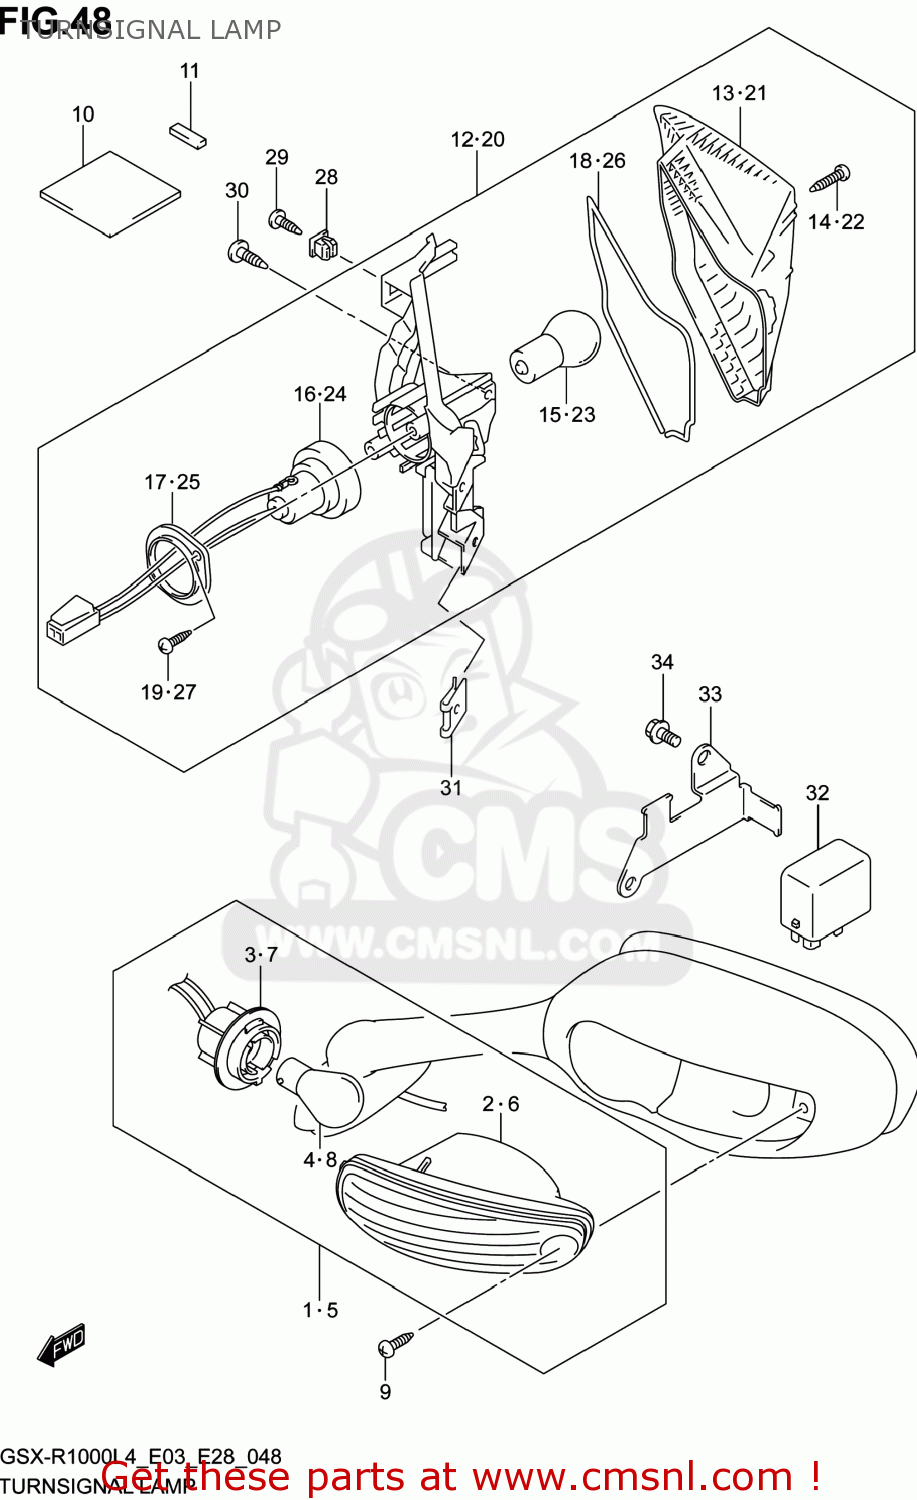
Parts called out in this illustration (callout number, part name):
1	LAMP ASSY,FR TURN SIGNAL,R
2	LAMP UNIT,R
3	SOCKET,R
4	BULB(12V21W,AMBER)
5	LAMP ASSY,FR TURN SIGNAL,L
6	LAMP UNIT,L
7	SOCKET,L
8	BULB(12V21W,AMBER)
9	SCREW(4X20)
10	CUSHION(40X20X5)
11	TAPE,FR TURNSIGNAL
12	LAMP ASSY,RR TURNSIGNAL,R
13	LENS,R
14	SCREW
15	BULB(12V21W,AMBER)
16	SOCKET & CORD,R
17	PLATE,RR COMBINATION
18	GASKET (NAS)
19	SCREW
20	LAMP ASSY,RR TURNSIGNAL,L
21	LENS,L
22	SCREW
23	BULB(12V21W,AMBER)
24	SOCKET & CORD,L
25	PLATE,RR COMBINATION
26	GASKET (NAS)
27	SCREW
28	NUT
29	SCREW
30	SCREW
31	NUT
32	RELAY ASSY,TURNSIGNAL LAMP
33	BRACKET,RELAY
34	BOLT
